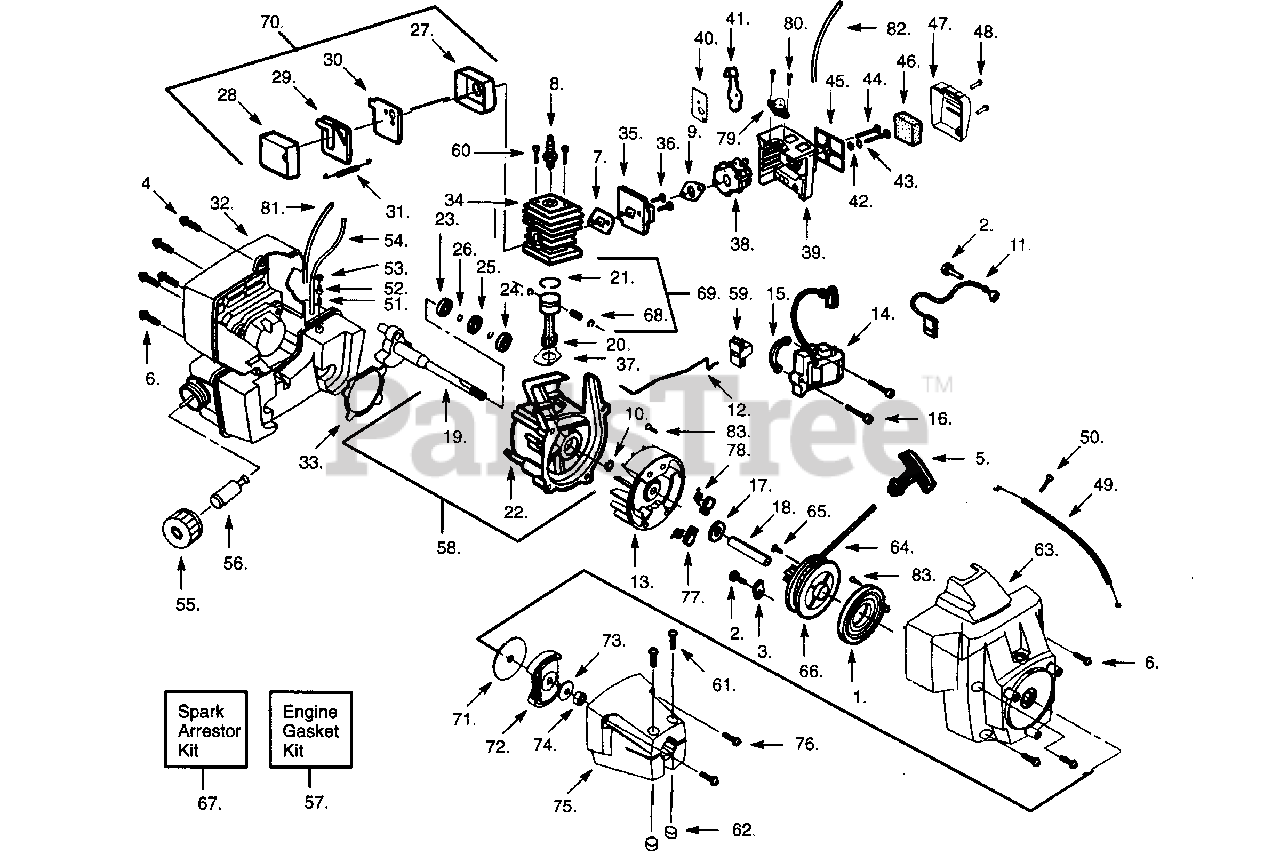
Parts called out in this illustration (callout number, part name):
1	Starter Spring
2	Screw-Lead Wire
3	Retainer
4	Screw-Shrd/Fan Hsg.
5	Starter Handle
6	Screw-Shroud
7	Cylinder/Carb. Gasket
8	Spark Plug (RCJ-8Y)
9	Gasket-Carb.
10	Retaining Ring C'case
11	Lead Wire
12	Switch Wire Form
13	Flywheel Ass'y.
14	Ignition Module
15	Spacer-Ignition Mod.
16	Screw-Ignition Mod.
17	Washer-Flywheel
18	Spacer-Flywheel
19	Crankshaft Ass'y.
20	Connecting Rod Ass'y.
21	Piston Ring
22	Crankcase Ass'y. (Incl. 23-26)
23	Inner Bearing
24	Outer Bearing
25	C'case Seal
26	Retain Ring-C'shaft
27	Muffler Body
28	Muffler Cover
29	Muffler Baffle-Exit
30	Muffler Baffle-First
31	Muffler Spring
32	Shroud & Tank Assy.
33	Gasket-C'case
34	Cylinder
35	Carb. Adaptor
36	Screw-Carb. Adap.
37	Gasket-Cylinder
38	Carburetor WT-380 (Incl. Limiter Caps)
40	Choke Plate
41	Choke Shutter
42	Wave Washer
43	Choke Spacer
44	Screw-Carb.
45	Filter Plate
46	Air Filter Foam
47	Air Filter Cover
48	Screw-Air Filter
49	Throttle Cable Ass'y.
50	Screw-Throttle Cab.
51	Check Valve
53	Retainer
54	Fuel Line-Tnk/Carb.
55	Fuel Cap Ass'y.
56	Fuel Pickup Ass'y.
57	Engine Gasket Kit (Incl. 7, 9, 33, 37)
58	C'case & C'shaft Assy. (Incl. 10,19,22-26)
59	Switch Button
60	Screw-Cylinder
61	Screw-Pinch Clamp
62	Locknut-Pinch Clmp
63	Fan Housing
64	Rope Kit
65	Screw-Rope Retain.
66	Starter Pulley
67	Spark Arrestor Kit
68	Piston Pin Retainer
69	Piston Kit (Incl. 21,68, & Pin)
70	Muffler Kit
71	Washer-Clutch
72	Clutch Ass'y.
73	Washer-Clutch
74	Nut-Clutch
75	Clutch Hsg.
76	Screw-Clutch Hsg.
77	Starter Dog
78	Starter Spring
79	Primer Bulb Ass'y.
80	Screw-Primer Bulb
81	Fuel Line-Prim./Tnk.
82	Fuel Line-Carb/Prim.
83	Screw-Flywheel
